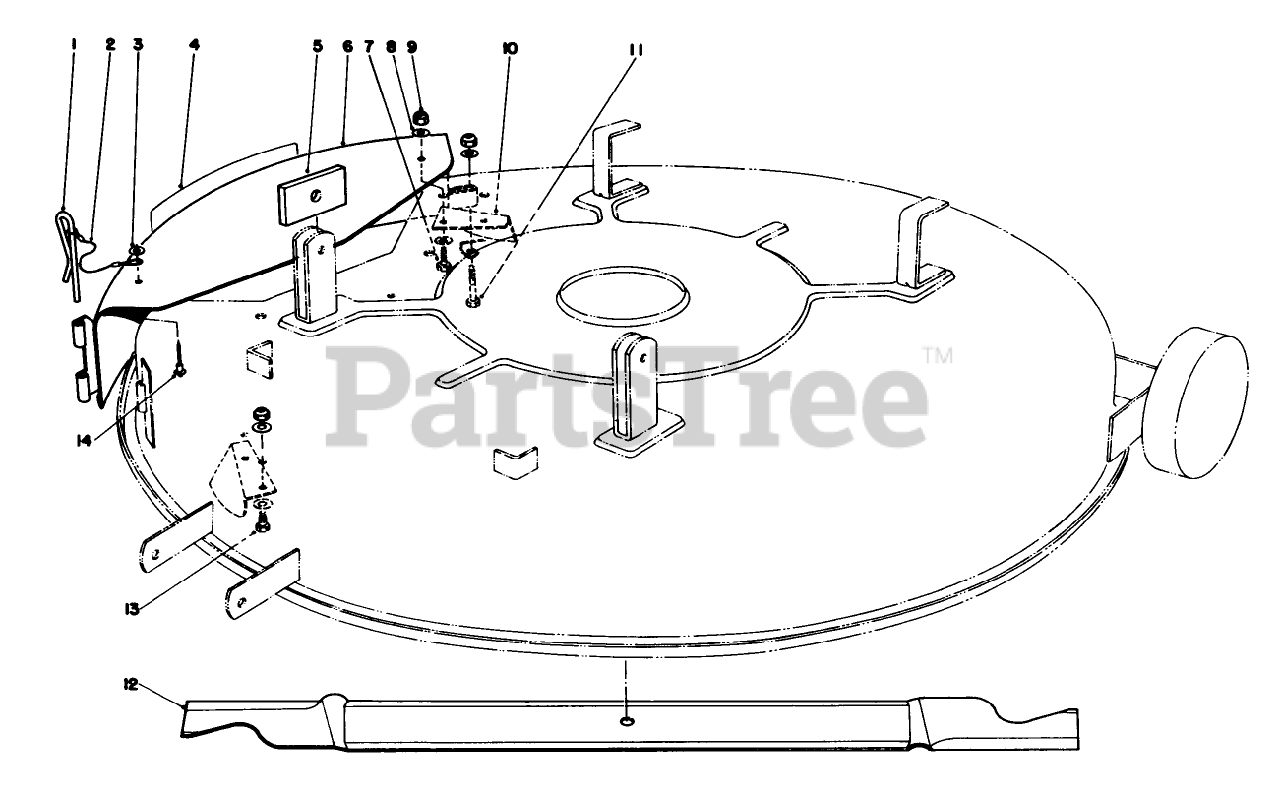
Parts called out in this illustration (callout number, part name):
1	PIN-LOCKING, CHUTE
2	LANYARD
3	WASHER-PLAIN
6	MULCHER COVER ASM (BLACK)
7	SCREW-HH
8	WASHER-PLAIN
9	NUT-LOCK, NI
10	KICKER *B
11	SCREW-HH
13	SCREW-HH
14	RIVET-BLIND
